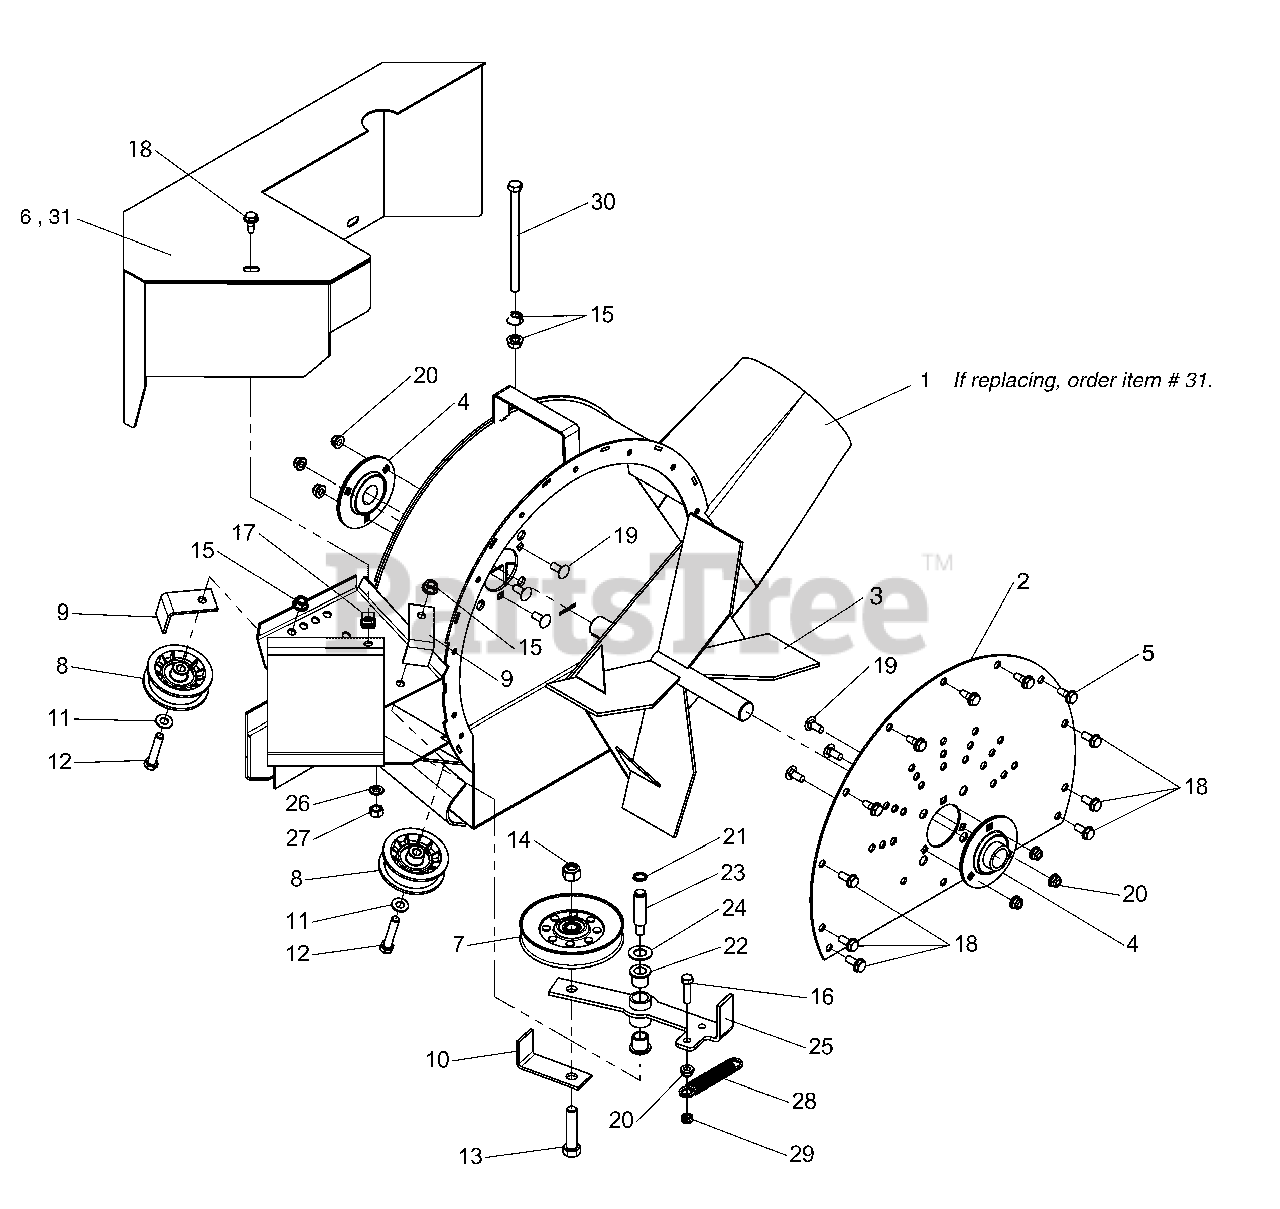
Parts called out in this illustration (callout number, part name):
1	**WELD, BLOWER HOUSING - FAST VAC - BLK
2	PLATE, BACK - BLK
3	WELD, IMPELLER, FAST VAC BLOWER
4	BEARING, FLANGE, 1" BORE
5	BOLT, 5/16-18 X 3/4, SELF-TAPPING
6	WELD, BELT GUARD, BLOWER - BLK
7	PULLEY, IDLER, V-NOTCH, 5
8	PULLEY, IDLER, 2.75 DIA X .376 ID
9	KEEPER, BELT - BLK
10	RETAINER, BELT - BLK
11	WASHER, 3/8 SAE
12	BOLT, 3/8-16 X 2 GD5 YZ
13	BOLT, 1/2-13 X 2-1/2 GD5
14	NUT, 1/2-13 HEX NYLON LOCK
15	NUT, 3/8-16 HEX NYLOCK FLANGE
16	BOLT, 5/16-18 X 1-1/4 GD5 YZ
17	BODY CLIP, 5/16-18 X 1/2 DEEP
18	HFLB, 5/16C X5/8 GR5 YZ
19	BOLT, 5/16-18 X 3/4", CARRIAGE
20	NUT, 5/16-18 HEX NYLOCK FLANGE
21	RETAINING RING, 1/2
22	BEARING, FLANGE, 9/16
23	STUD, IDLER, YELLOW
24	FW, .594X1.125X.063 YZ
25	WELD, IDLER ARM - BLK
26	WASHER, 3/8" SPLIT LOCK
27	NUT, 3/8-24 HEX
28	SPRING, EXTENSION
29	HCLN, 5/16-18 GR5 YZ
30	BOLT, 3/8-16 X 6 GD5 YZ
31	WELD, FAST-VAC GUARD - BLK
